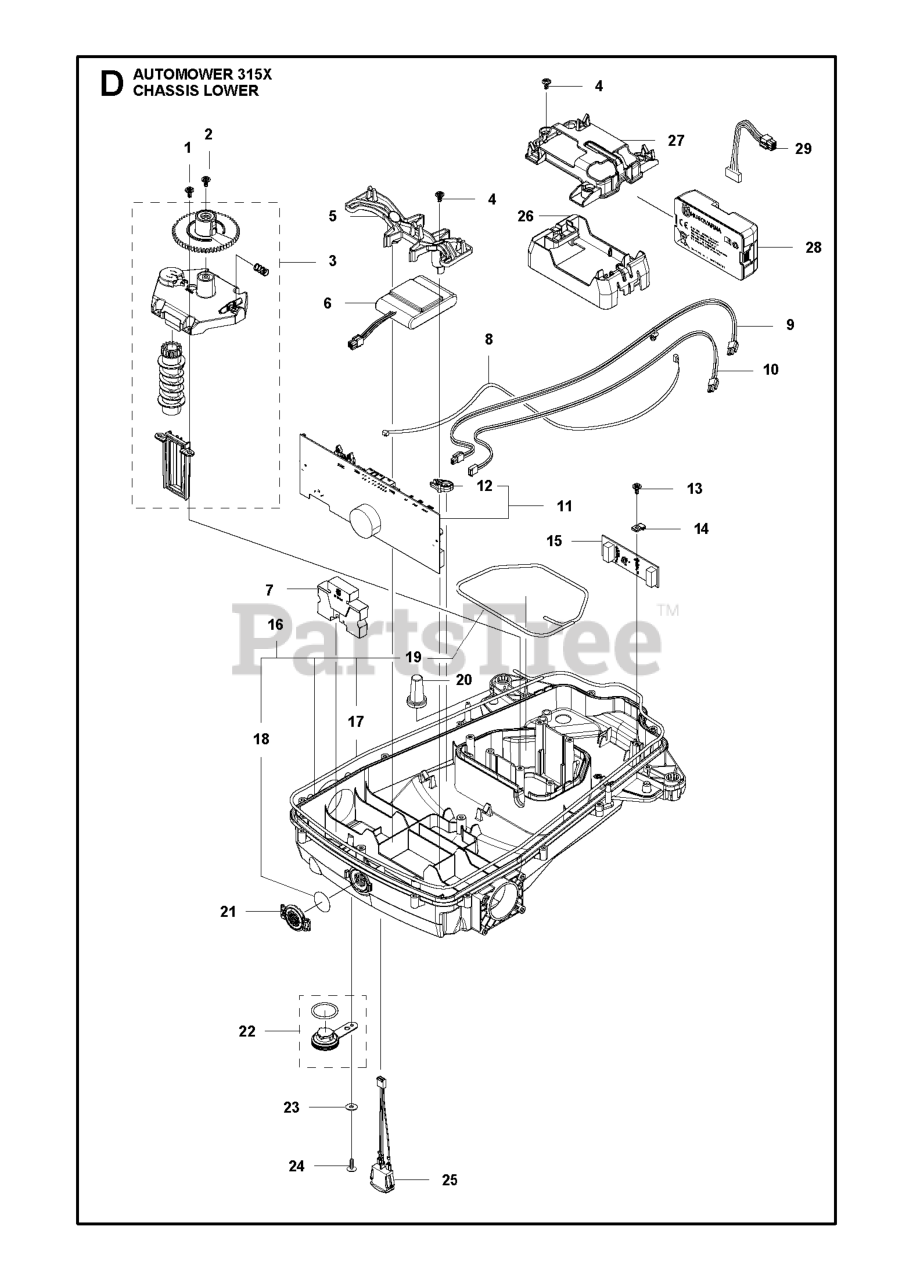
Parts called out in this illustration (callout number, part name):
1	SCREW ITXPANT
2	SCREW ITXPANT
3	COVER KIT
4	SCREW ITXPANT
5	HOLDER BATTERY AND WEIGHT
6	BATTERY LI-ION
7	WEIGHT 470G
8	LOOM LOOP SENSOR
9	LOOM CHARGING LINK
10	WIRING ASSY LED LIGHT EXTENSIO
11	PRINTED CIRCUIT ASSY MAIN BOAR
12	CLIP PCB
13	SCREW ITXPANT
14	CLAMP PCB
15	PRINTED CIRCUIT ASSY LOOP SENS
16	CHASSIS KIT LOWER
17	SEALING STRIP P 15 CHASSI LOW
18	KIT AIR FILTER KIT 305 - 10 PC
19	SEALING STRIP P15 UPPER
20	COLUMN FRONT
21	COVER AIR FILTER
22	PLUG KIT
23	WASHER
24	SCREW ITXPANT
25	LOOM ON/ OFF
28	BATTERY:18V, 2.0AH, 36.0WH TYP
29	WIRING ASSY BATTERY CABLE
